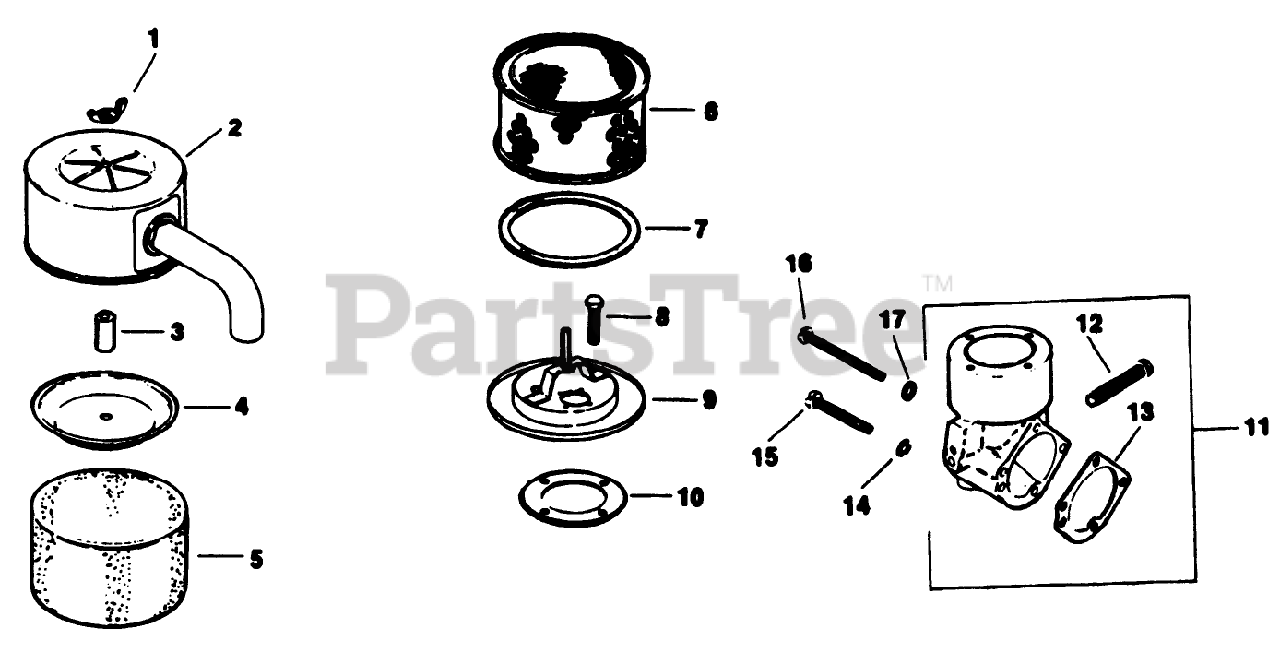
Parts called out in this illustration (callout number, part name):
1	Nut-Wing
2	Cover-Air Cleaner
3	Seal
4	Cover-Inner
5	Element
6	Element
7	Seal
8	Screw-H.C.
9	Base-Air Cleaner
10	Gasket-Air Cleaner
11	Kit-Elbow (Incl. Ref. #12 & 13)
12	Screw-H.C
13	Gasket-Elbow
14	Washer
15	Screw-R.H.M.
16	Screw-R.H.M.
17	Washer
